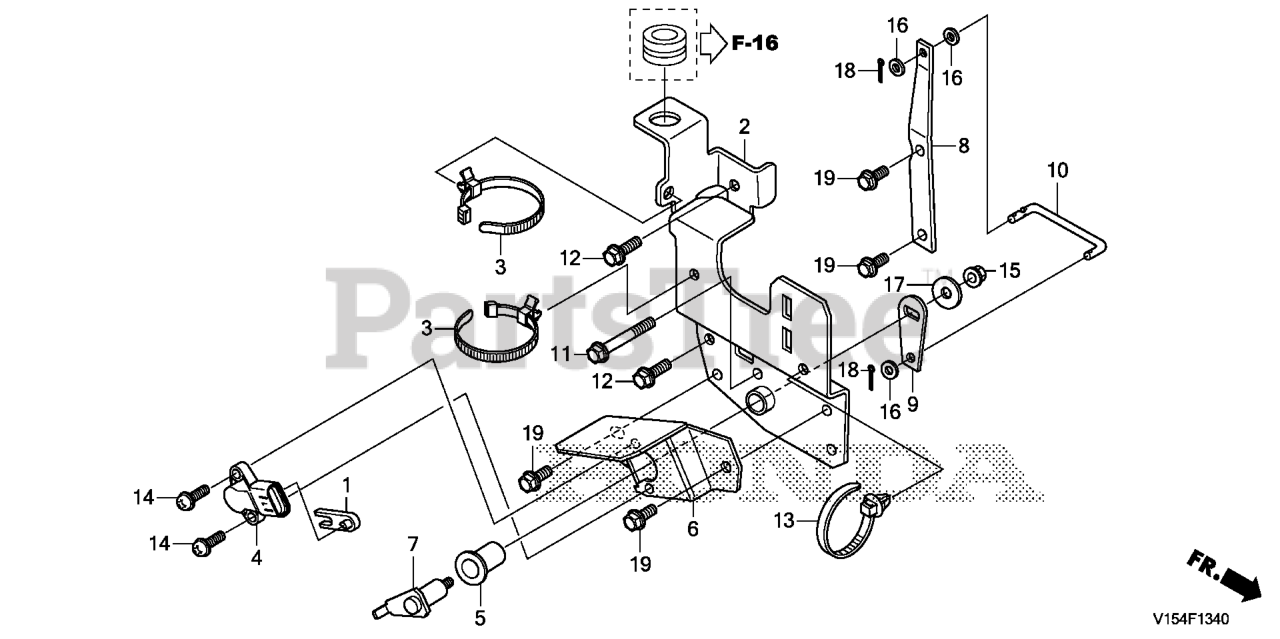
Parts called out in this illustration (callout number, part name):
1	ARM, TURN LEVER
2	BRACKET, CONNECTOR
3	BAND, WIRE HARNESS
4	SENSOR ASSY., ANGLE
5	BUSH, PARKING BRAKE
6	BRACKET, HEIGHT SENSOR
7	SHAFT, HEIGHT SENSOR
8	ARM A, HEIGHT SENSOR
9	ARM B, HEIGHT SENSOR
10	ROD, HEIGHT SENSOR
11	BOLT, FLANGE (6X40)
12	BOLT, FLANGE (6X14)
14	SCREW-WASHER (5X18) (NOT AVAILABLE)
15	NUT, FLANGE (6MM)
16	WASHER, PLAIN (5MM)
17	WASHER, PLAIN (6MM)
18	PIN, COTTER (1.6X12)
19	BOLT, FLANGE (6X12) Use up to Engine SN 1543277.
